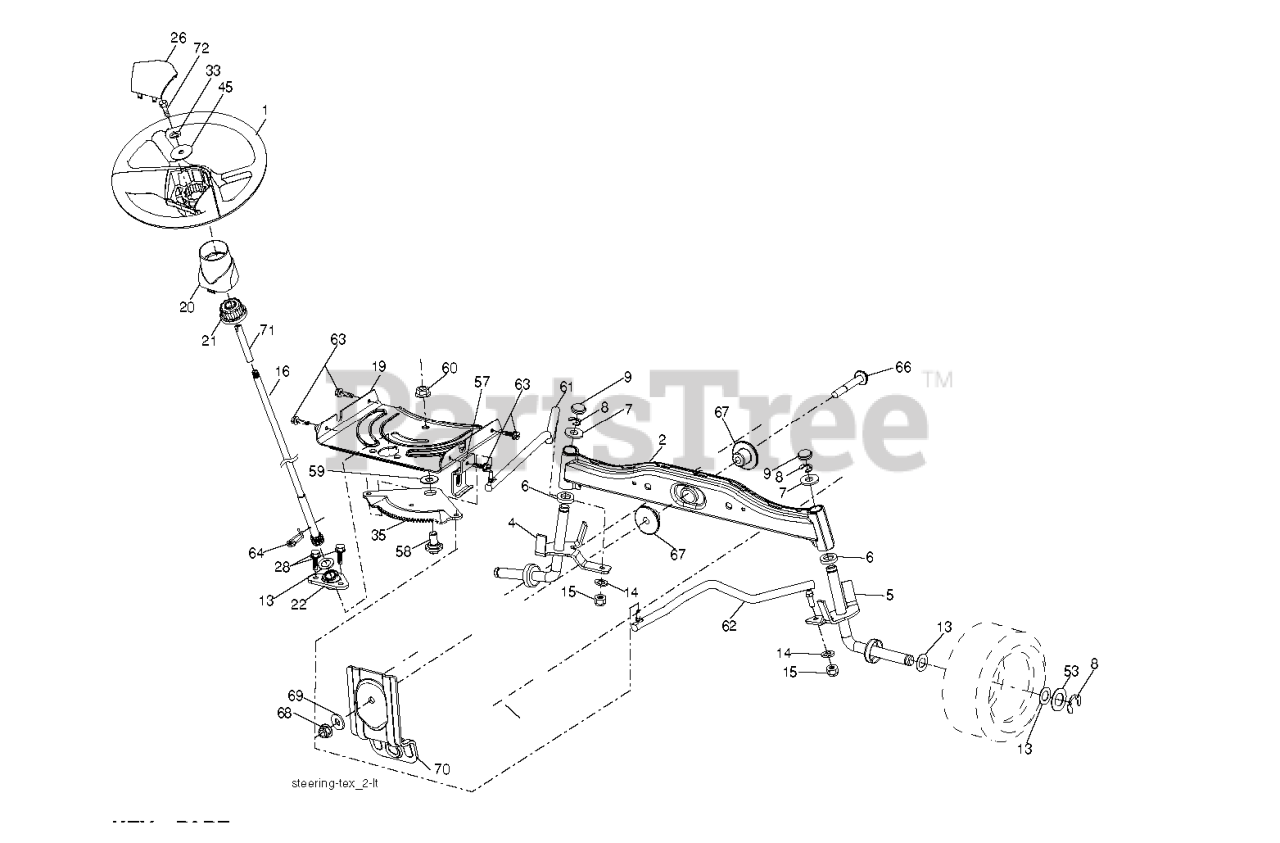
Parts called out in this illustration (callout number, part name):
1	WHEEL.STEERING.LEGEND2.GRY
2	AXLE.CAST.IRON
4	SPINDLE.WELDED.LH.15"TEX
5	SPINDLE.WELDED.RH.15"T
6	THRUST WASHER
9	CAP.SPINDLE.BLACK
14	WASHER, LOCK 3/8
15	NUT CROWNLOCK 3/8-24
16	SHAFT STEERING
19	PLATE.STEER.DDL.NLT/NG
20	BOOT, STEERING
21	ADAPTER, WHEEL STNG..
22	BUSHING.ASM.STEERING.A
26	INSERT.CAP.STRG.WH.GRAY
28	SCREW, 3/8-16X3/4
33	WASHER.LOCK.HVY.HLCL.SPR.5/16
35	GEAR.SECTOR.PLATE.DDL.
45	WASHER.11/32
53	WASHER.HARDENED
57	BRACKET.UPSTOP.TEX
58	BOLT.SHOULDER.SECTOR.P
59	WASHER.THURST.SECTOR.S
60	NUT FLANGE LOCK 5/8-11
61	DRAGLINK.LH.BALLSTUD.D
62	DRAGLINK.RH.BALLSTUD.D
63	SCREW
64	RETAINER.CLIP.SPRING.S
66	BOLT HEX FGHD 7/16-14 X 3 SERR
67	BUSHING.PM.FRONT AXLE
68	NUT.LOCK.FLANGE.7/16
69	WASHER.1.5X.505X.118
70	BRKT.DECK.SUSPENSION.F
71	SHAFT EXTENSION STEERING
72	BOLT YT
